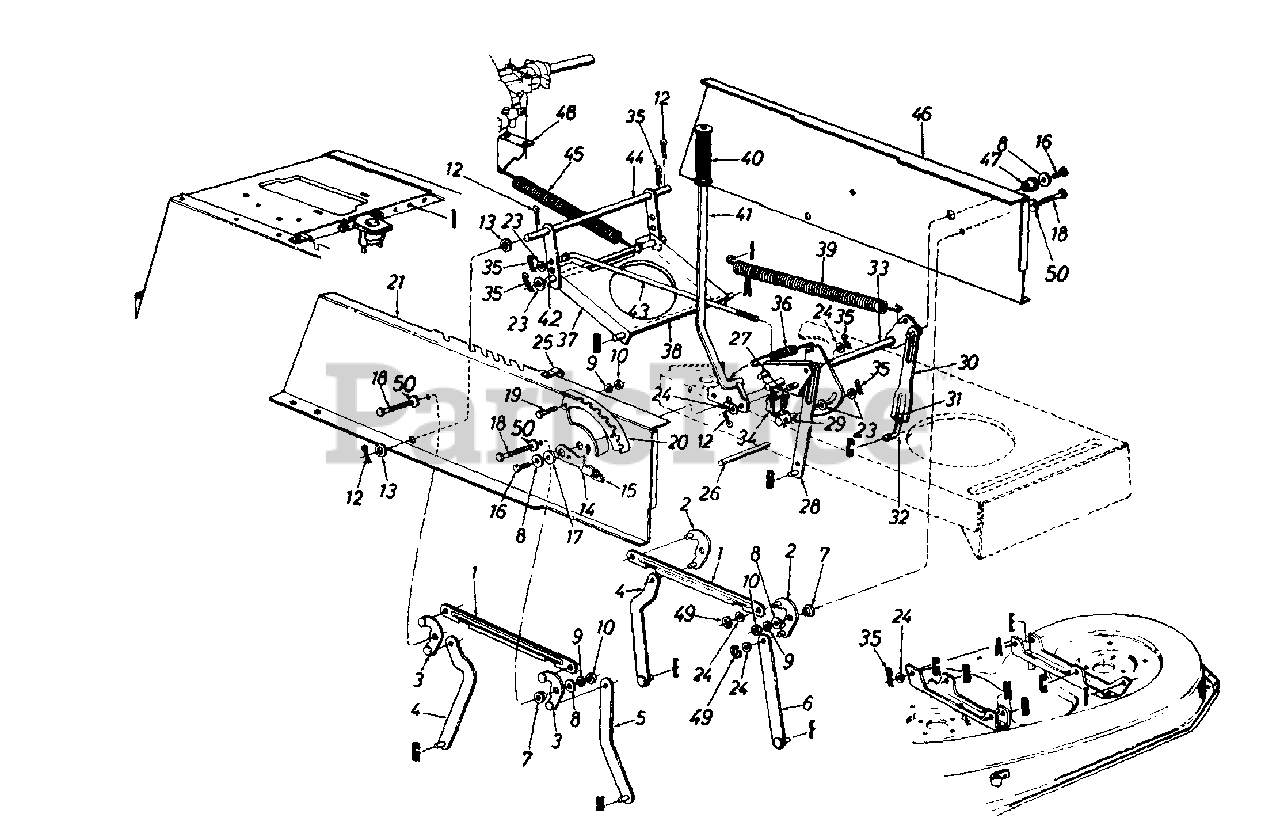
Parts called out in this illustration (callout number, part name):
3	Pivot Link Ass'y. - R.H. (Uses "E"-Ring)
7	Shld. Spacer .318" I.D.
8	Fl-Wash. .344" I.D. x .62" O.D.
9	L-Wash. 5/16" I.D.
10	Hex Nut 5/16-18 Thd.
12	Cotter Pin 1/8" Dia.
13	Fl-Wash. .635" I.D. x 1.0" O.D.
14	Height Adj. Stop Lever Ass'y.
15	Knob
16	Hex Wash. TT-Tap Scr. 5/16-18 x .75" Lg.
17	Flange Brg. .63" I.D.
18	Hex Wash. Hd. Scr. 5/16-18 x .875" Lg.
19	Hex Bolt 5/16-18 x .75" Lg.
20	Index Brkt.
24	Fl-Wash. .531" I.D. x .93" O.D.
25	Clamp
26	Running Board Rod
27	Hex Wash. Hd. Tap Scr.
31	Hex Nut 1/2-20 Thd. (Gr. 5)
32	Lift Link Adjuster
35	Inter. Cotter Pin 3/8" Dia.
36	Extension Spring
39	Extension Spring
40	Grip (Lift Handle)
41	Deck Lift Handle Ass'y.
42	Shaft 3/8" Dia. x 9.34" Lg.
43	Disengagement Rod
44	Stabilizer Shaft Ass'y.
45	Extension Spring 7.58" Lg.
48	Spring Retainer Brkt.
49	"E"-Ring
50	Bell-Wash. .325" I.D.
